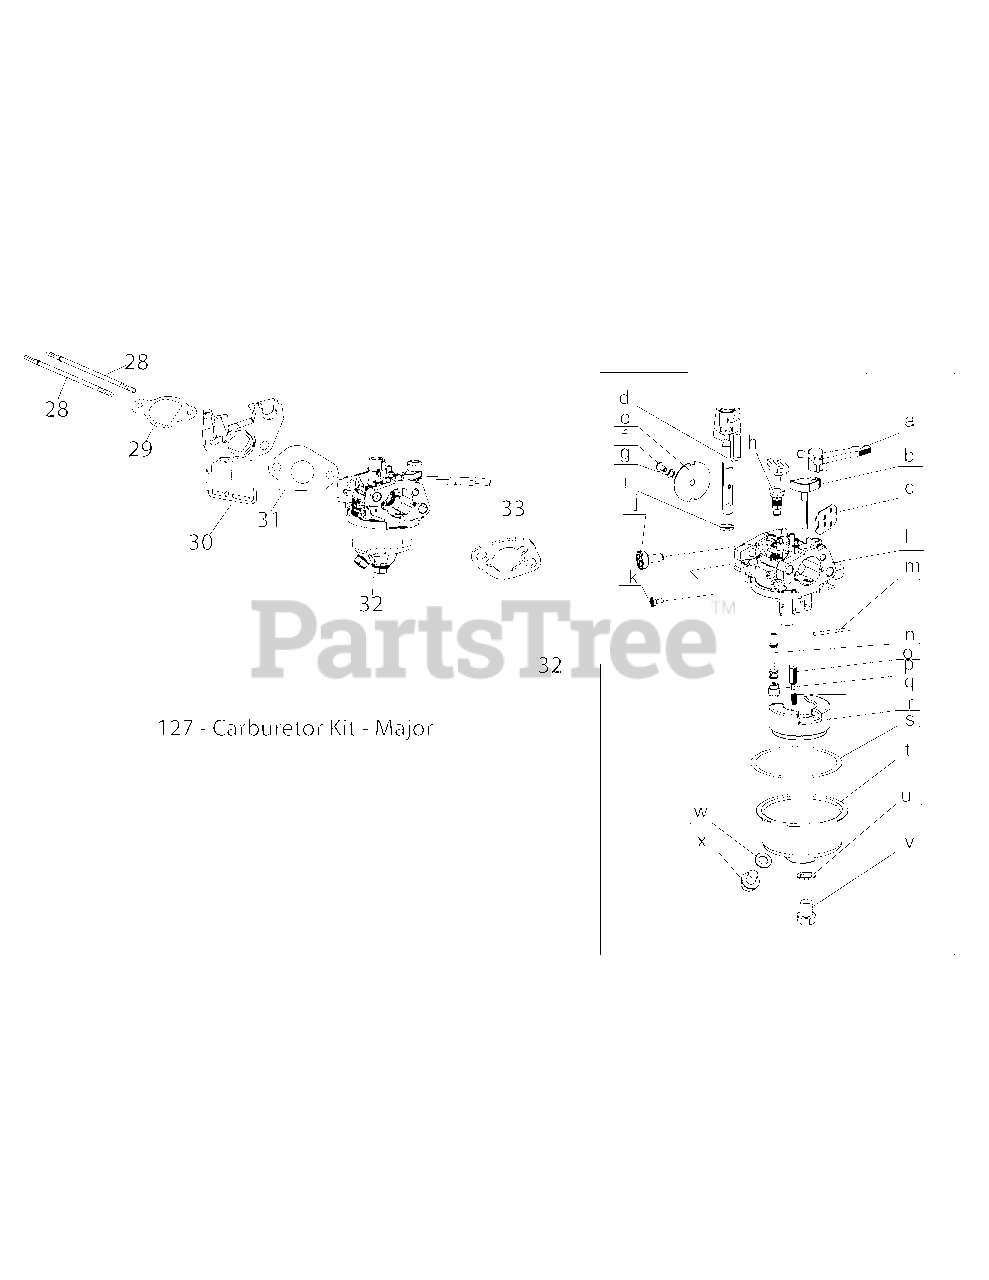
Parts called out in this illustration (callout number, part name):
28	Stud M6×110
29	Carburetor Insulator Gasket
30	Carburetor Insulator
31	Carburetor Gasket
32	Carburetor Assembly
33	Carburetor Gasket Plate
127	Carburetor Kit - Major
